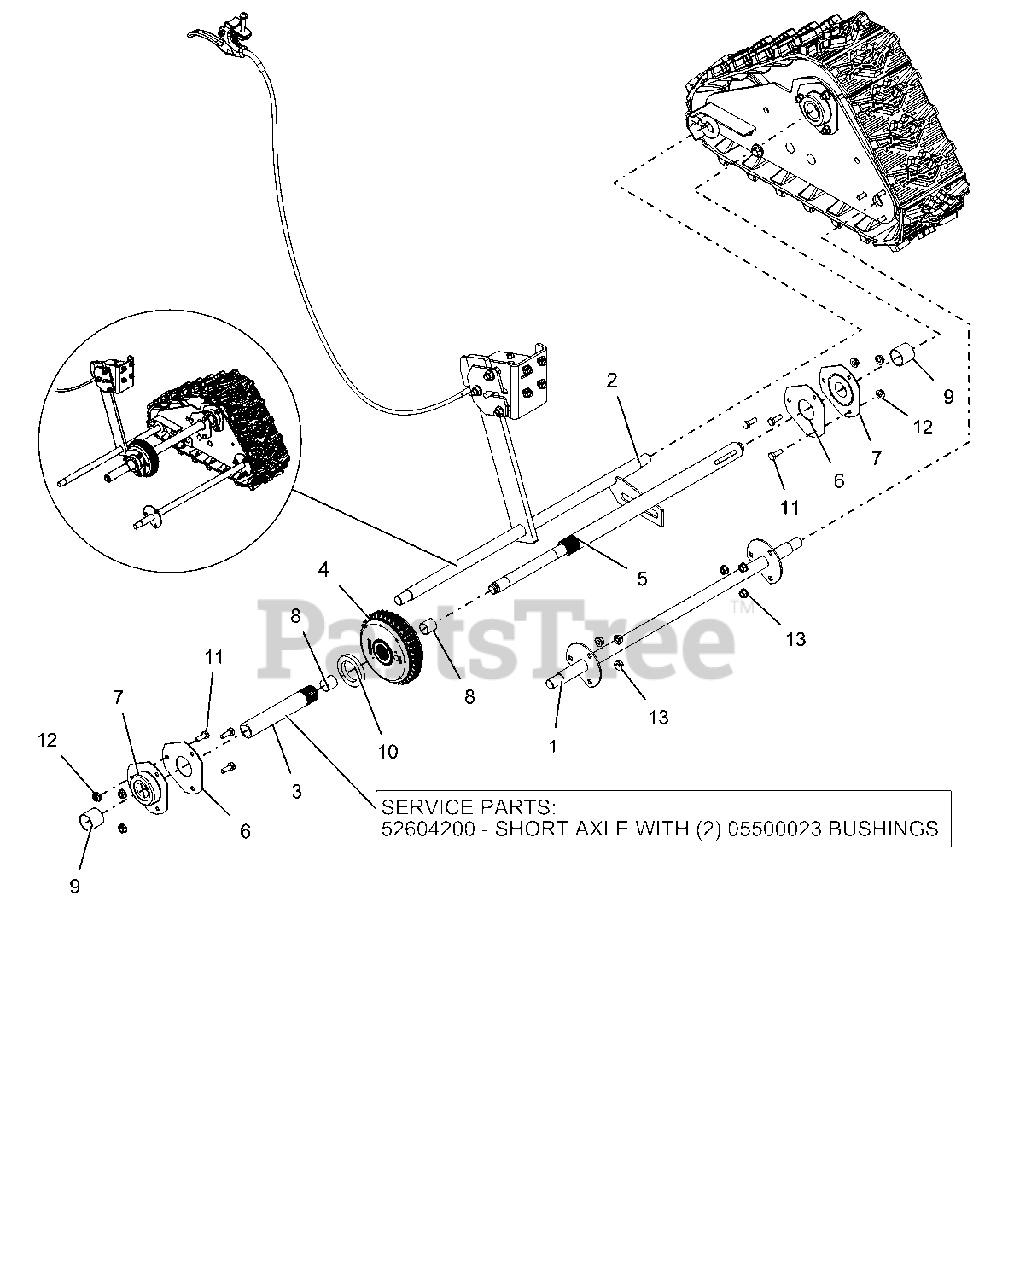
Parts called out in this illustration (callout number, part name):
1	AXLE, FRONT - PRO
2	AXLE, REAR - PRO TRACK
3	BSHG-SLV .706X.764X.75 BRZ
3	AXLE, SHORT-TRACK DIFFERENTIAL
3	AXLE, SHORT-TRACK W/BUSHINGS
4	DIFFERENTIAL, AUTOMATIC
5	AXLE, LONG-PRO AUTO DIFF
6	PLATE, BEARING SPACER
7	BRG-FLG 1.003/1.000 3 BOLT
8	BSHG-SLV .706X.764X.75 BRZ
9	BSHG-SLV, 1.012X1.125X1.00
10	WSHR-FL-NY 1.38X2.00X.25
11	@BLT-HEX .25-20X.75 GR5 YWZC
12	@NUT-LK-CTR-FLG .25-20 YWZC
13	@NUT-LK-TOP-FLG .25-20 YWZC
